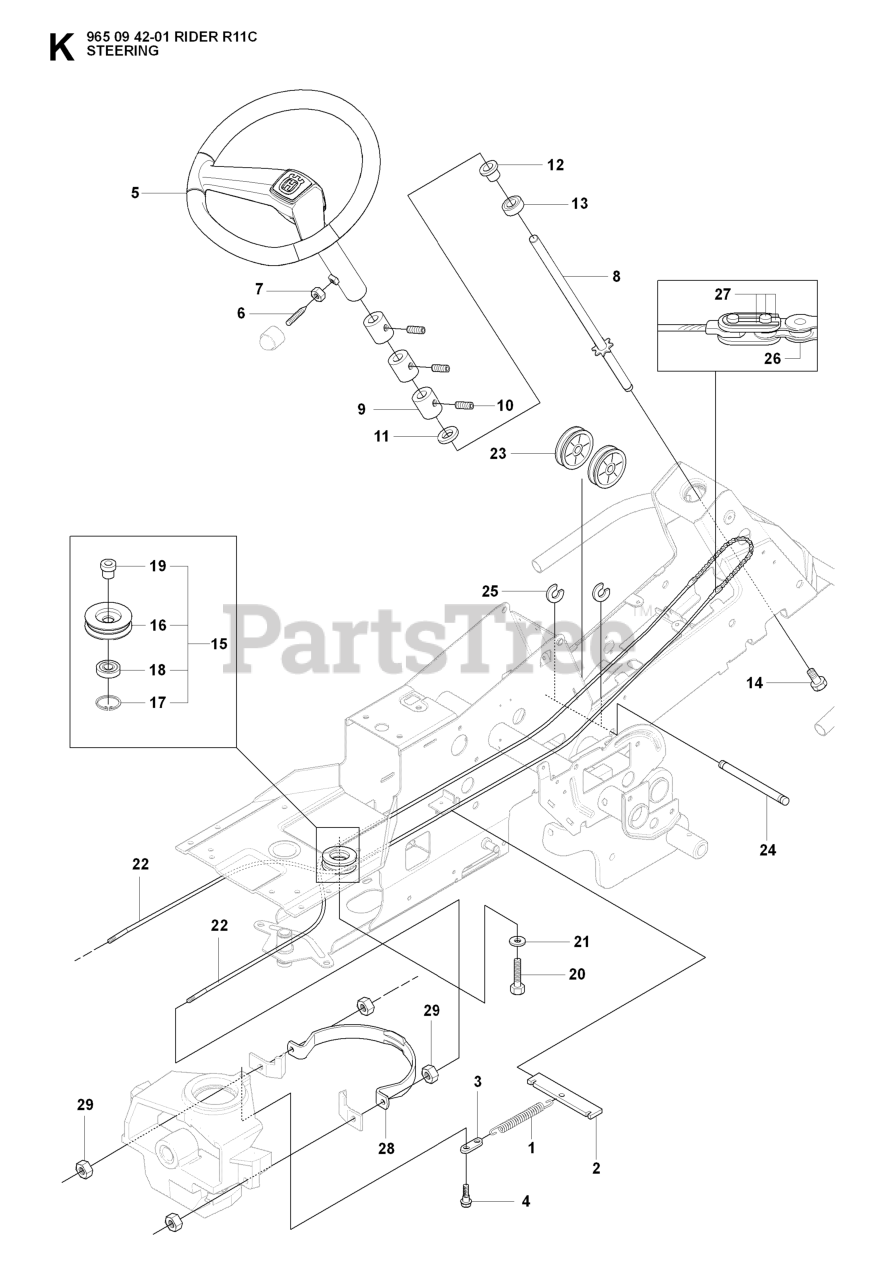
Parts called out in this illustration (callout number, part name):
2	SPRING BRACKET
5	STEERING WHEEL
7	NUT
8	ROD STEERING ASSY
9	SPACER
13	BALL BEARING 6004-2RS1
17	CIRCLIP SGH 47
18	BALL-BEARING 6204-2RS
22	RP STEERING CABLE COMPLETE
25	RETAINING RING
26	STEERING CHAIN
28	WIRE GUIDE
29	NUT
